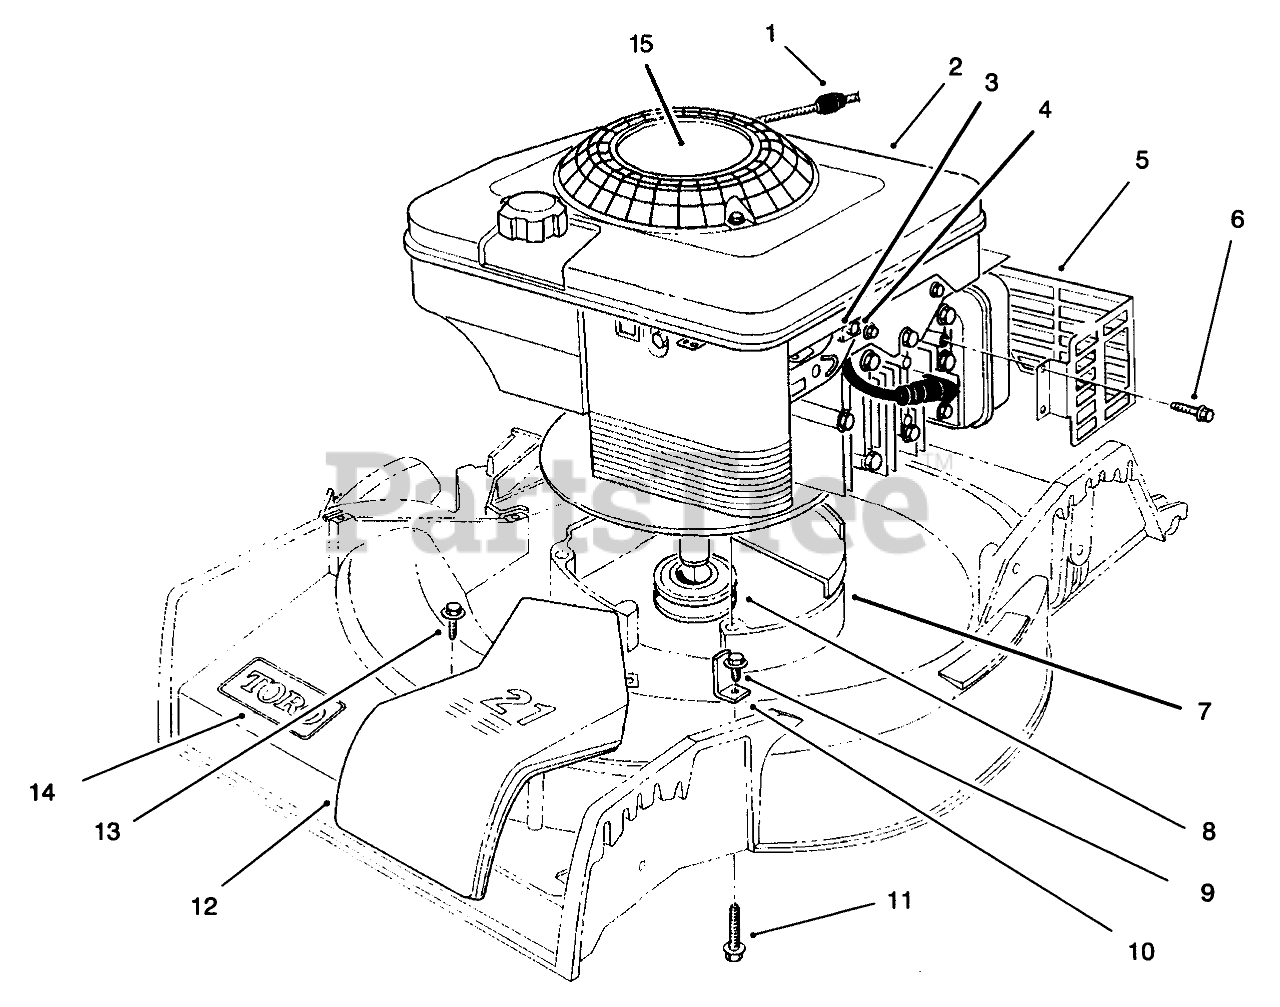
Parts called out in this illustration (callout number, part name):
1	STOP-ROPE
3	CLAMP-CASING
4	SCREW-CLAMP
5	SHIELD-MUFFLER
6	SCREW-HWH
7	HOUSING CAP
8	PULLEY-DRIVER
9	SCREW-HWHTF
10	BELT GUIDE
11	3/8-16 X 2-3/4 CAPSCR
12	BELT COVER 21" S D
13	SCREW-HWH
14	DECAL
15	DECAL-ENGINE F/W ENGINE
